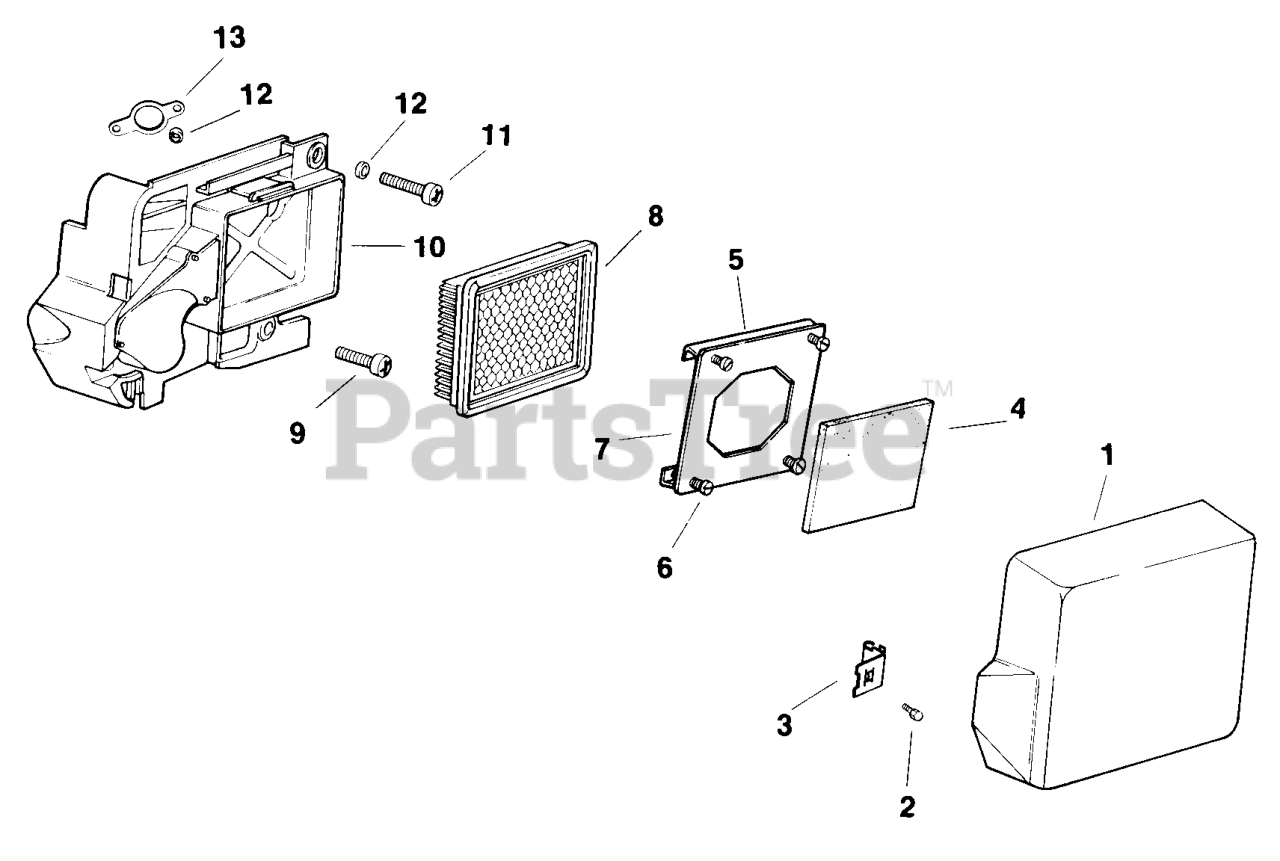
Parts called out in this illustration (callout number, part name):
1	COVER - DISCONTINUED
4	PRE-CLEANER -DISCONTINUED
5	BRACKET - DISCONTINUED
6	Screw, bracket retainer M5-20
7	RETAINER - DISCONTINUED
9	Screw, A/C base mounting M6x1.0x30.5
10	BASE - DISCONTINUED
11	Screw, A/C base mounting M6x1.0x35.5
13	GASKET, CARBURETOR
